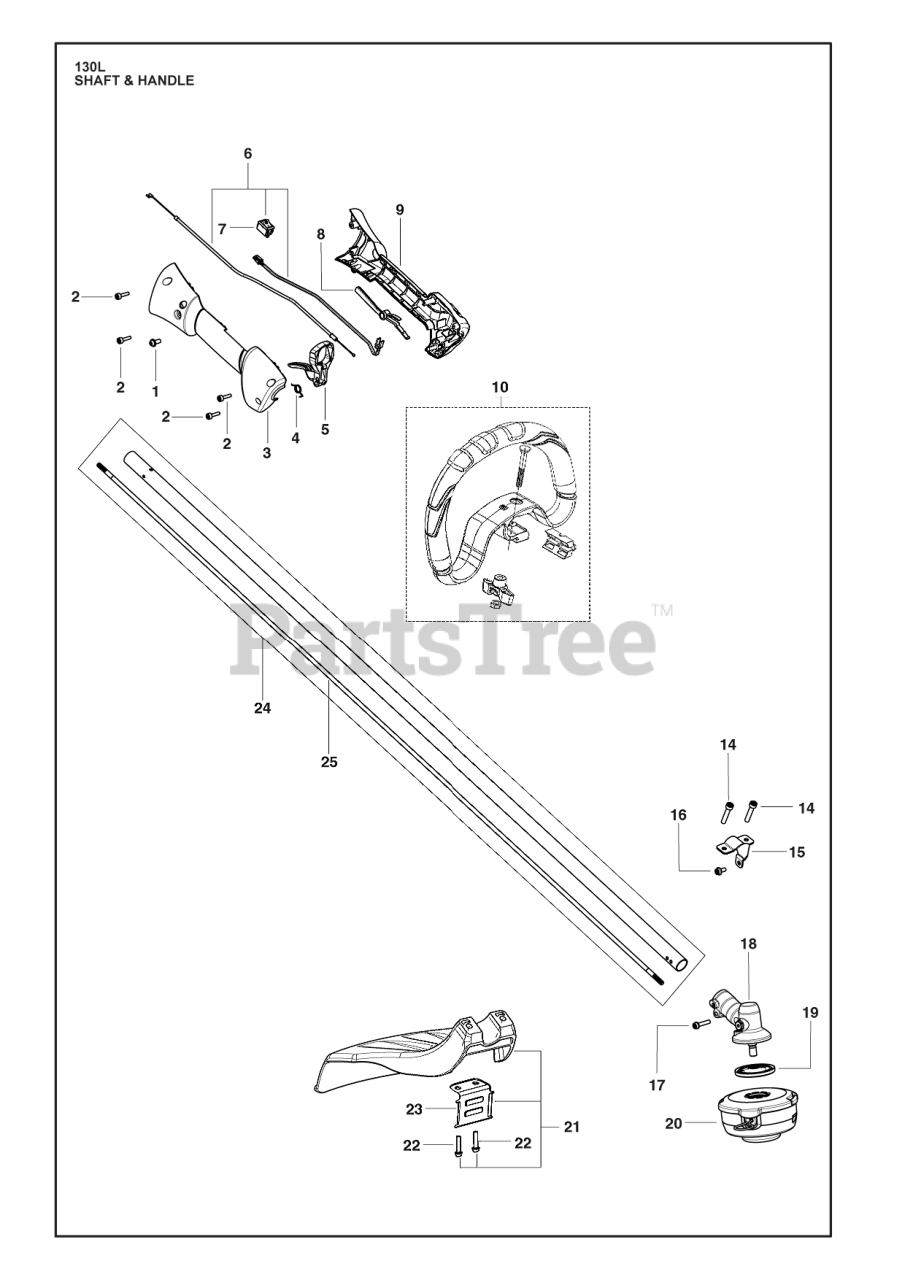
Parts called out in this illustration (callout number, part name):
1	SCREW
2	SCREW
3	HOUSING THROTTLE
4	SPRING TRIGGER
5	TRIGGER THROTTLE HVA ORANGE
6	ASSY CABLE / WIRE HARNESS
7	SWITCH
8	THROTTLE LOCKOUT HVA ORANGE
9	HOUSING THROTTLE
10	HANDLES
14	BOLT, TORX
15	BRACKET SHIELD
16	BOLT
17	SCREW
18	GEAR HEAD ASSY
19	DRIVE DISC
20	TRIMMER HEAD T25
21	GUARD ASSY KIT
22	SCREW
23	BLADE
24	DRIVE SHAFT ASSY
25	FLEXSHAFT 57"
